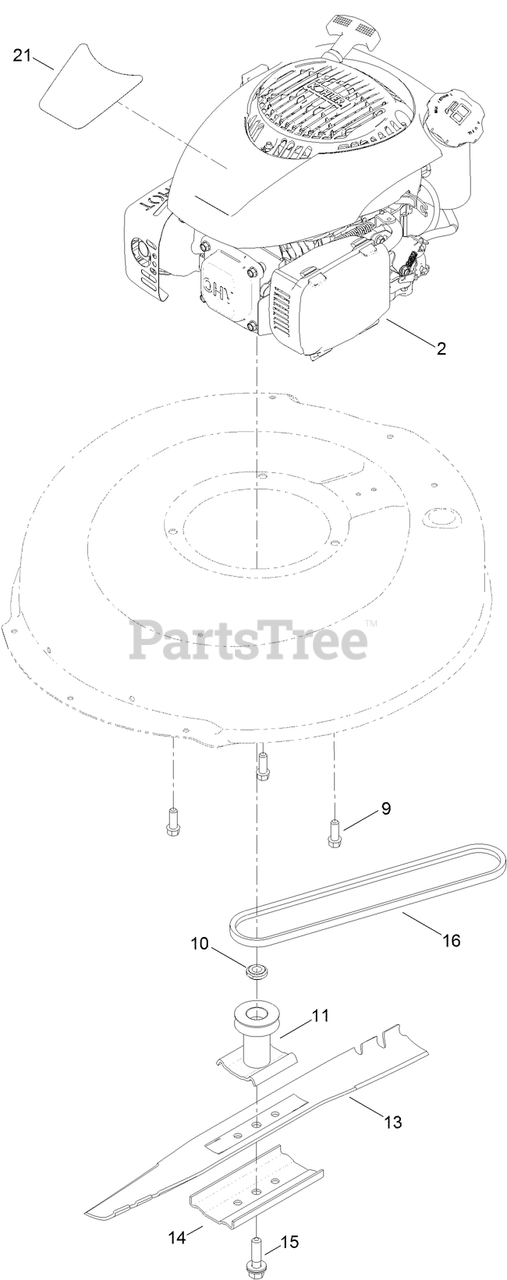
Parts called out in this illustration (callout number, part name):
9	SCREW-TAPTITE
10	SPACER-DRIVER
11	DRIVER-BLADE
14	SUPPORT-BLADE
15	BOLT-BLADE
